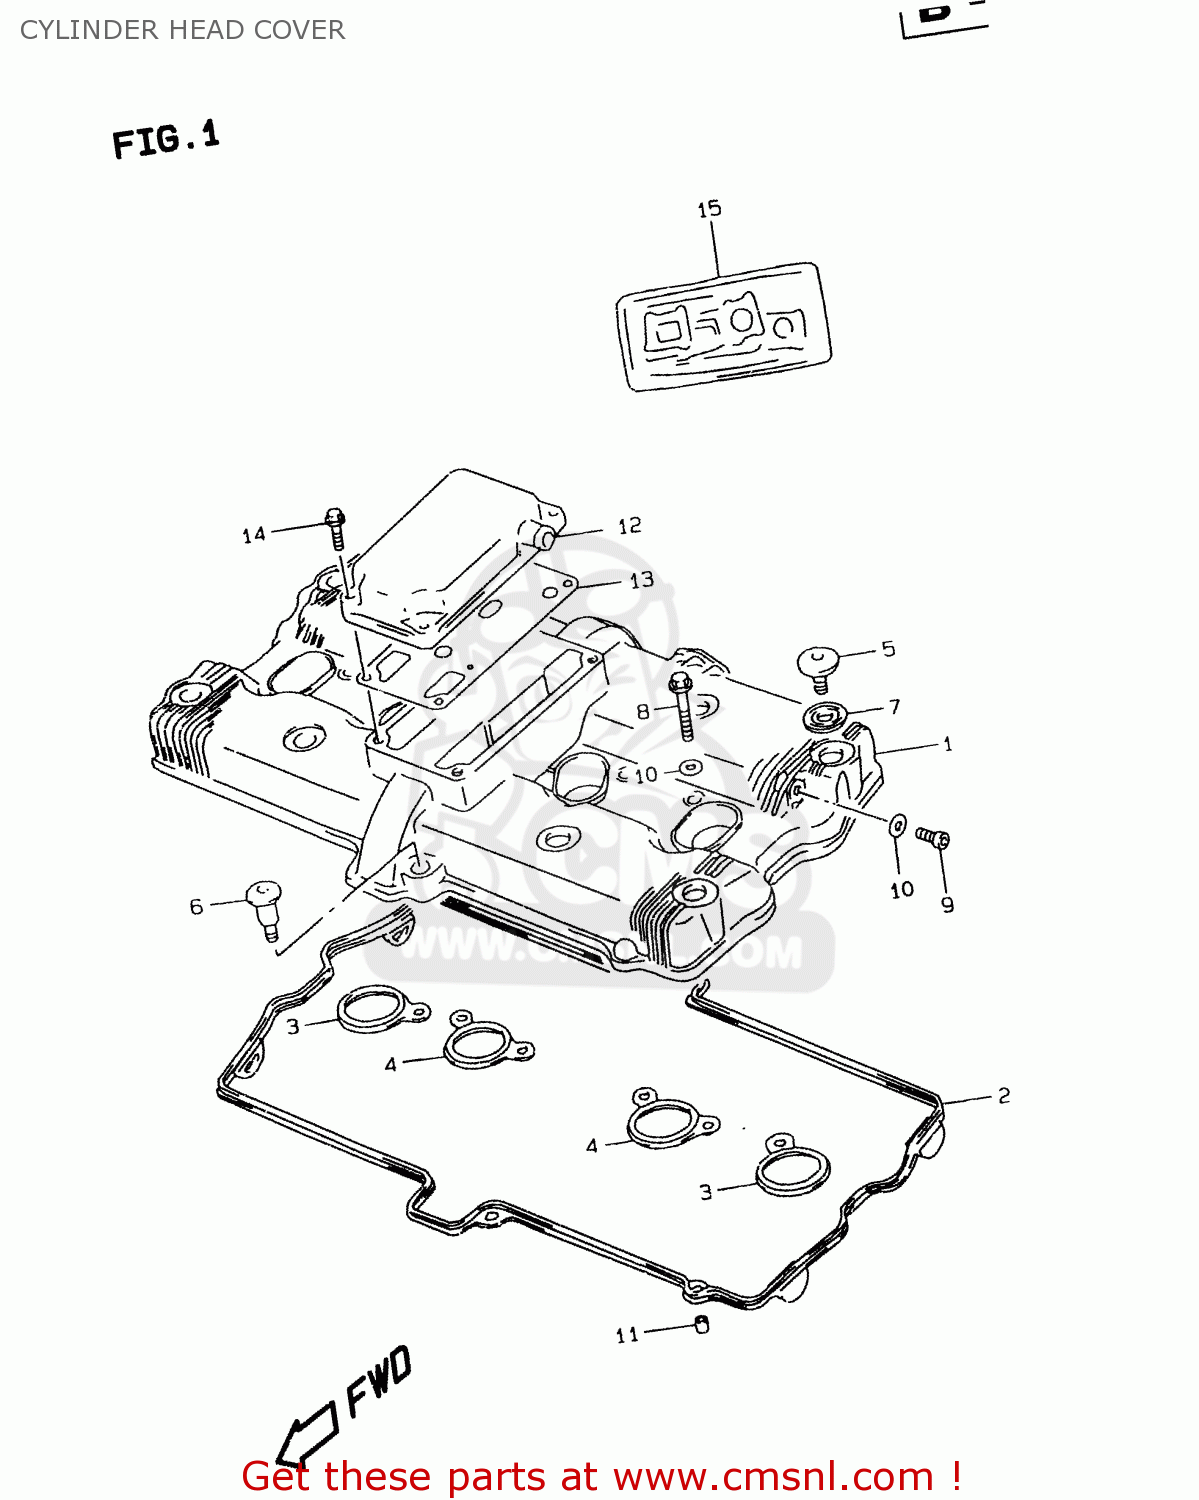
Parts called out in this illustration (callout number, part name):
1	COVER,CYLINDER HEAD
2	GASKET,CYLINDER HEAD COVER (NAS)
3	GASKET,HEAD COVER NO.2 (NAS)
4	GASKET,HEAD COVER NO.3 (NAS)
5	BOLT(7X17.5)
6	BOLT(7X31)
7	WASHER(10.6X25.5X2.3)
8	BOLT,UNION 8X35
9	PLUG
10	GASKET 8.2X14X1 (NAS)
11	PIN
12	COVER,BREATHER
13	GASKET,BREATHER COVER
14	BOLT
15	GASKET SET (NAS)
